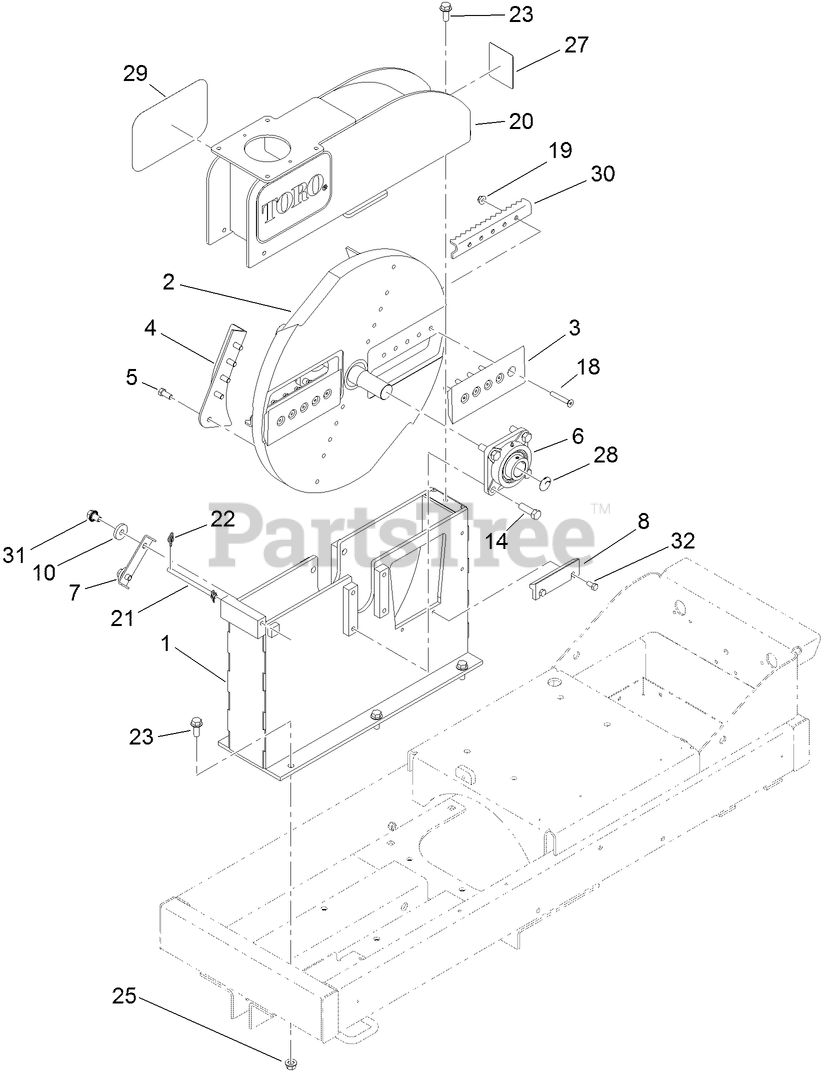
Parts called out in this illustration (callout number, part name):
1	FLYWHEEL HOUSING ASM
2	FLYWHEEL ASM
3	BLADE-CHIPPER
4	PADDLE WHEEL ASM
5	SCREW-HH
6	BEARING ASM
7	PLATE-COVER
8	BLOCK-CUTTER
10	WASHER
14	SCREW-HH
18	BOLT-HSFH
19	NUT-HF, NI
20	FLYWHEEL COVER ASM
21	PIN-HINGE
22	PIN-COTTER
23	SCREW-HHF
25	NUT-LOCK
27	DECAL-DANGER
28	DECAL-INDICATOR, ROTATION
29	DECAL
30	PLATE-MULCH
31	SCREW-HHF
32	SCREW-HH
